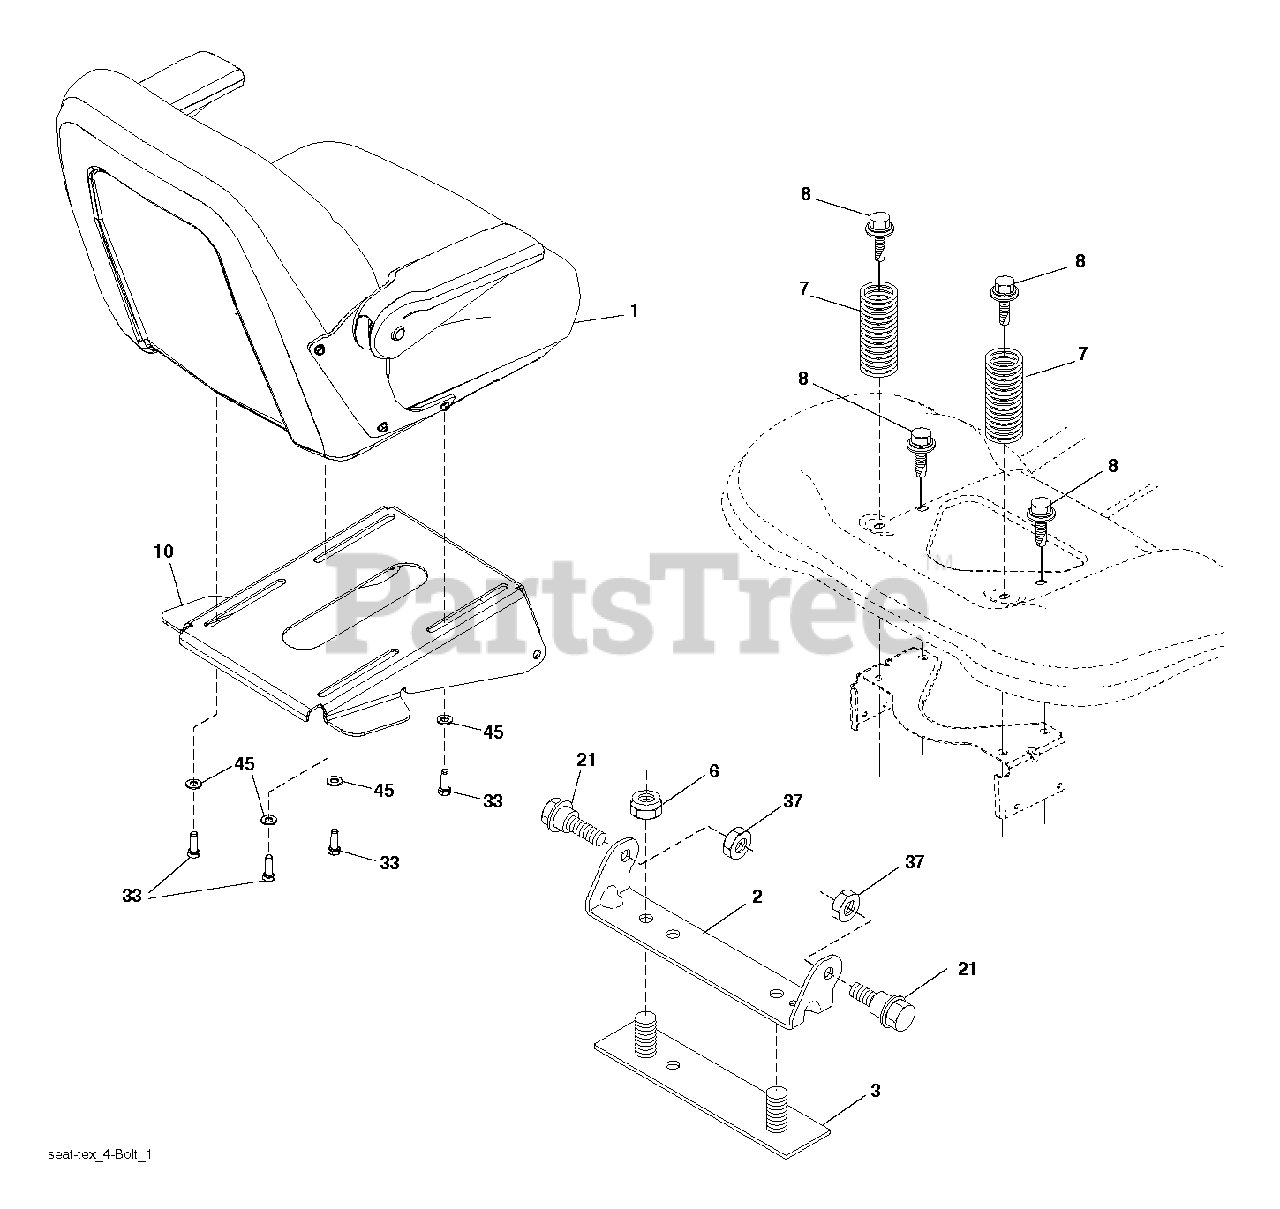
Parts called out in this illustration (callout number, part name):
1	SEAT.MILSCO.18".WITH.ARMREST
2	BRKT.PIVOT.FENDER
6	NUT
7	SPRING COMPRESSION
8	BOLT, 5/16-18 X 1 3/4
10	PAN.SEAT.4-BOLT.7.5X7.431
21	BOLT.SHOULDER.5/16-18
33	BOLT.FIN.HEX.5/16-18UNC X 1.00
37	NUT.71038.31-18.HEX.NYLOCK
